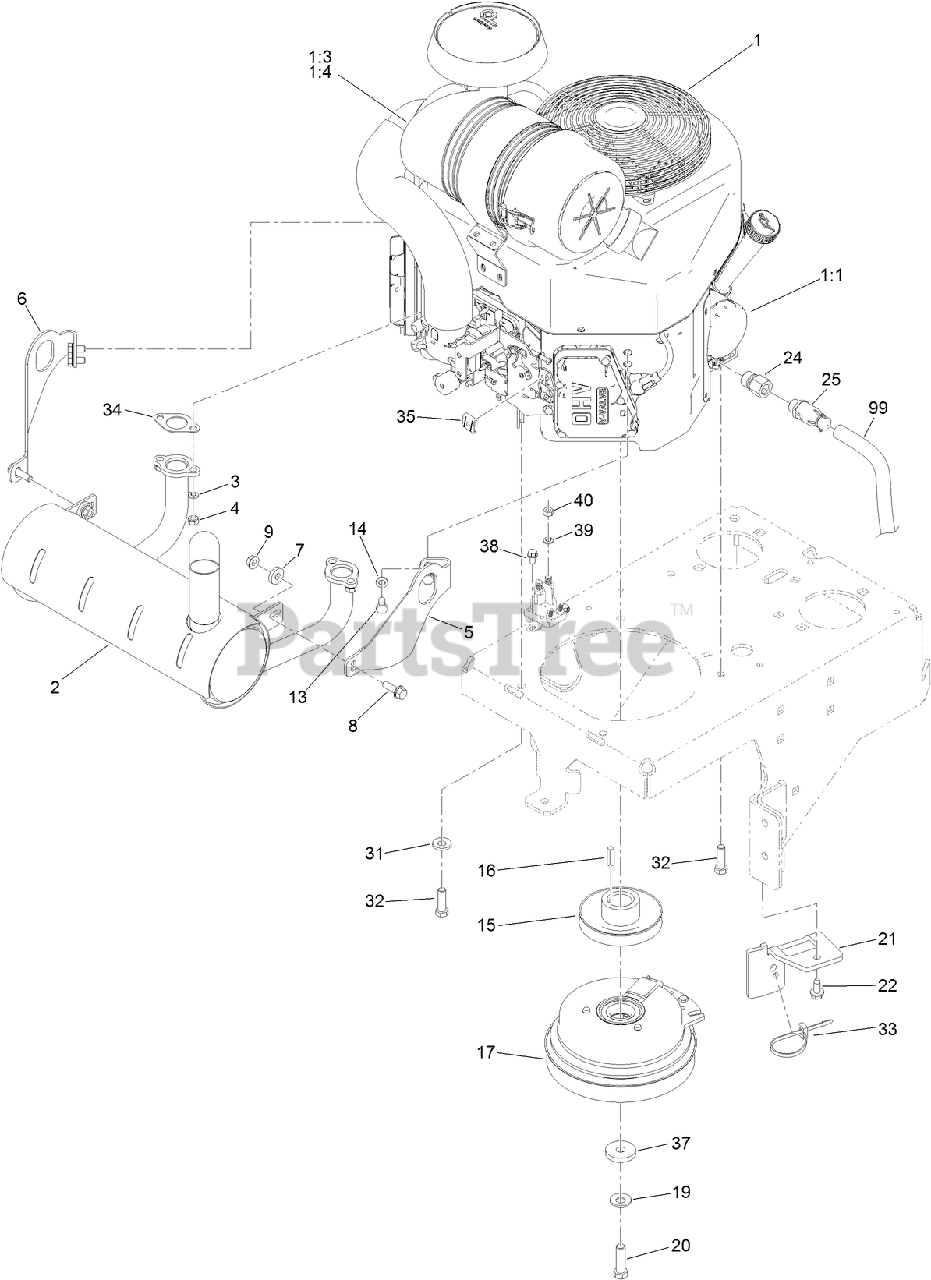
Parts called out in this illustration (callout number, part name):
1:1	FILTER-OIL
1:3	ELEMENT-FILTER, AIR (OUTER)
1:4	ELEMENT-FILTER, AIR (INNER)
2	MUFFLER
3	WASHER-LOCK
5	BRACKET-MUFFLER, LH
6	BRACKET-MUFFLER, RH
7	SPACER
8	SCREW-HHF
9	NUT-HF
13	SCREW-HH
14	WASHER-LOCK
15	PULLEY
17	CLUTCH-200CMS
19	WASHER-SPRING
20	SCREW-HH
21	BRACKET-ANCHOR, CLUTCH
22	SCREW-HWHTF
24	Adapter
25	VALVE-DRAIN, OIL
31	WASHER-BELLEVILLE
32	SCREW-HH
33	TIE-CABLE
34	GASKET-EXHAUST
35	CLAMP-CABLE
37	WASHER
38	SCREW-HWH
39	WASHER-LOCK
40	NUT-HEX
99	HOSE-DRAIN, OIL
